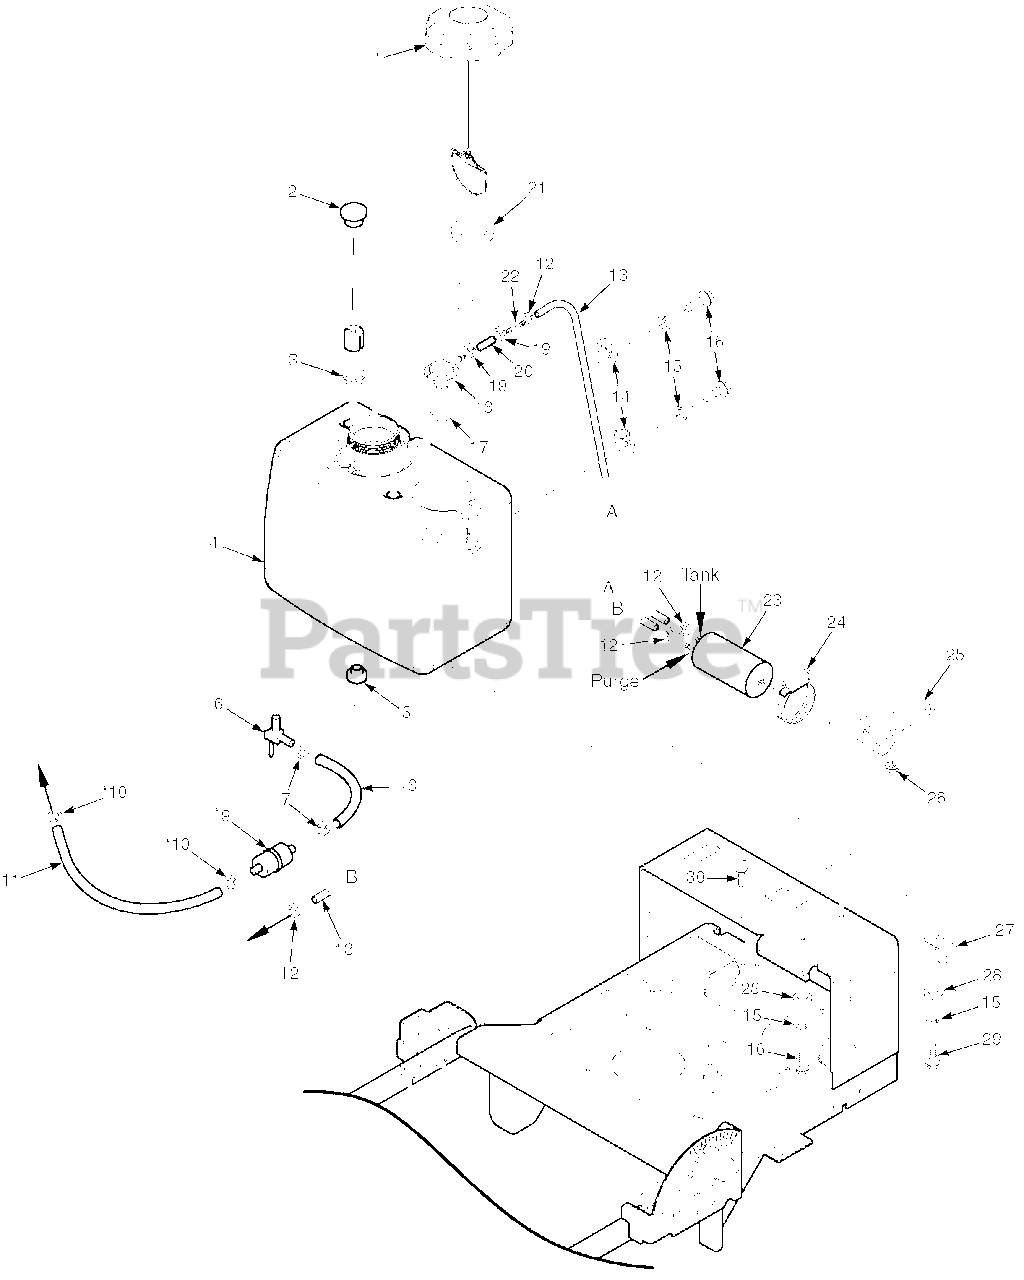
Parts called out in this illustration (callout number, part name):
1	Fuel Cap w/ Tether
2	Fuel Gauge Assembly
3	Seal, Fuel Gauge
4	Fuel Tank Assembly
5	Bushing, .56 Dia. Viton
6	Ball Valve w/Screen
7	Clamp, Fuel Hose
8	Fuel Hose, 1/4" ID
9	Fuel Filter
10	Clamp, Fuel Hose
11	Fuel Hose
12	Clamp, Vapor Recovery Hose 3/16"
13	Hose, Vapor Recovery 3/16"
14	Clamp, 3/8"
15	Lockwasher, 5/16" Spring
16	Bolt, Hex Head 5/16-18 x 3/4"
17	Grommet, Viton
18	Fitting, Remote Vent
19	Clamp, Fuel Hose 7/32" ID
20	Hose, Vapor Recovery 1/4"
21	Tube, Fuel Tank Insert - 4"
22	Mender, 1/4 x 3/16 w/.02 Hole
23	Carbon Canister
25	Bracket, Canister Mounting
26	Nut, Serrated Flange 5/16-18
27	Clamp, 1/2"
28	Flatwasher, 5/16-.375 x .875 x .083
29	Bolt, Hex Head 5/16-18 x 1"
30	Bolt, Carriage 5/16-18 X 3/4"
